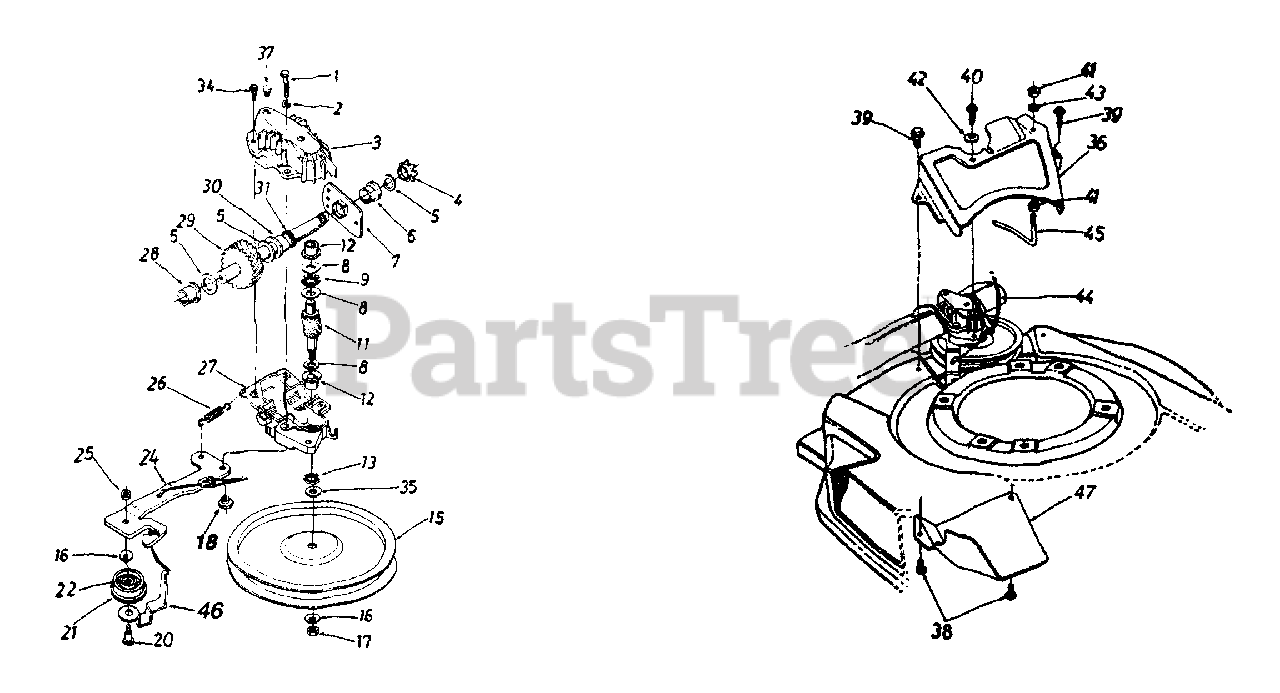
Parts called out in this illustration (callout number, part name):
1	Hex Bolt 1/4-20 x 1.25" Lg.
2	L-Wash. 1/4" I.D.
3	Upper Hsg. Half
4	#48 Sprocket 7 Tooth x 1/2 Pitch
5	Fl-Wash. 5/8" I.D. x .030
6	Hex Flange Brg. .631" I.D.
8	Thrust Wash. .362" I.D. x .70" O.D.
9	Thrust Bearing .375" I.D. x .812" O.D.
11	11 Tooth Helical Gear
12	Flange Bearing
13	Oil Seal
15	Fl-Pulley 5.06" I.D.
16	Bell-Wash. .265" I.D. x .75"
17	Hex Nut 1/4-28 L.H. Thd.
18	Shld. Spacer .375" Dia. x .170
20	Shld. Bolt .375" Dia. x .40"
21	Fl-Idler Plastic 1.50" Dia.
22	Needle Brg. .375" x .375"
24	Idler Brk't. Ass'y.
25	Hex Patch L-Nut 1/4-28 Thd.
26	Extension Spring 1.12" Lg.
27	Lower Hsg. Half
28	Flange Bearing .56 Dia.
29	Shaft Ass'y.
30	Flange Bearing .629 Dia.
31	Oil Seal .625 Dia.
34	Scr. AB #10-16:. .750 HxIndWsh.
35	Hex Washer .26" x .86"
38	Hex B-Tap Scr. 1/4-20: .375 Lg.
39	Hex AB-Tap Scr. 1/4 x .50" Lg.
40	Hex B-Tap Scr. 1/4 x .62" Lg.
41	Hex Nut 1/4-20 Thd.
42	Bell-Wash. .265" I.D. x .75"
43	L-Wash. 1/4" I.D.
44	S.P. Cable-48" Lg.
45	S.P. Belt Guard
46	Belt Guard
